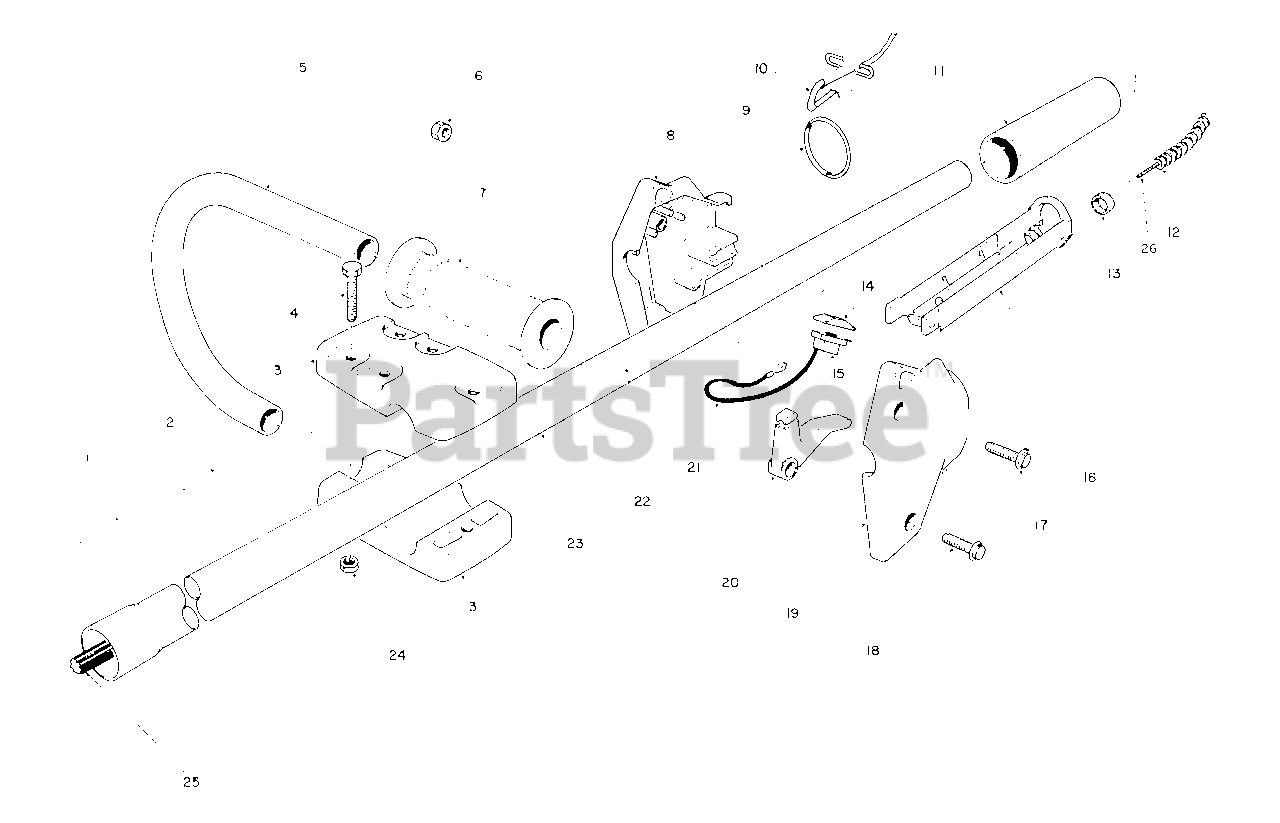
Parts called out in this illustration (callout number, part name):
1	Decal-TC 3510
2	Decal-Instructions
3	Clamp-Secondary
4	Screw-Hex. Hd. Machine
5	Handle-Secondary
6	Nut-Lock
7	Grip-Handle
8	Housing Assembly R.H.
9	Ring-Harness
10	Harness-Shoulder
11	Grip-Drive Housing
12	Cover-Cable
14	Cap-Switch
17	Screw-Hex. Hd. Cap
18	Screw-Hex. Hd. Cap
19	Housing Assembly-L.H.
20	Lever-Throttle
21	Wire Assembly
22	Decal-Danger
23	Tube Assembly
24	Nut-Lock
25	Shaft-Spline, Drive
26	Cable-Throttle
